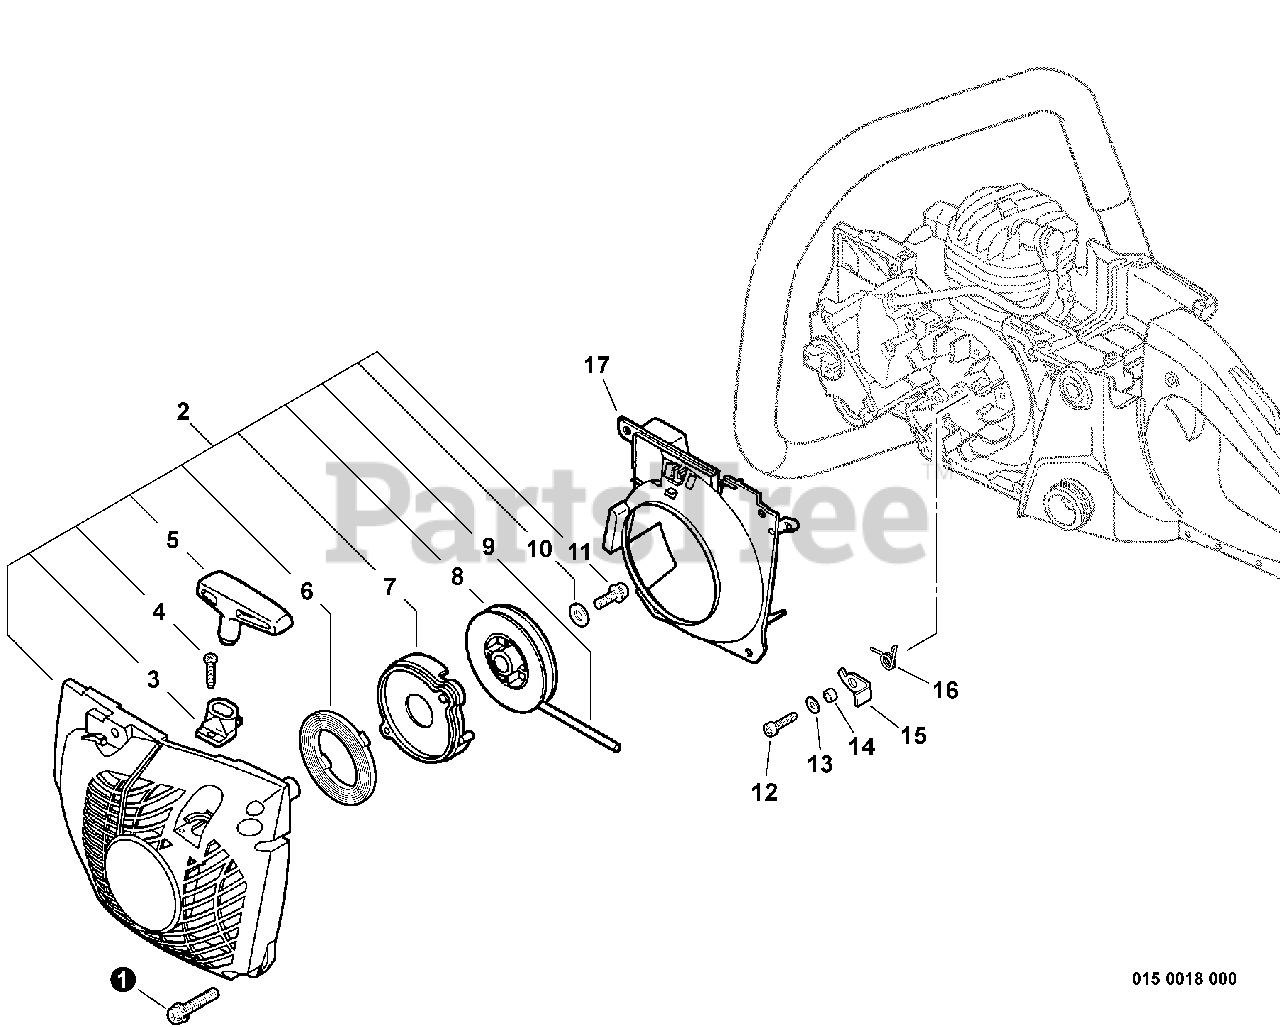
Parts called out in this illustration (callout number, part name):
1	SCREW - 5X18
2	STARTER ASSY - GRAY
3	GUIDE, ROPE
4	SCREW - 3X14
5	GRIP, STARTER
6	SPRING, REWIND
7	PLATE, STARTER
8	REEL, ROPE
9	ROPE, STARTER - 3.5X960
10	WASHER - 5
11	SCREW - 5X12
12	SCREW - 5X14
13	WASHER - 5
15	PAWL, STARTER
16	SPRING, RETURN
17	COVER, FAN
